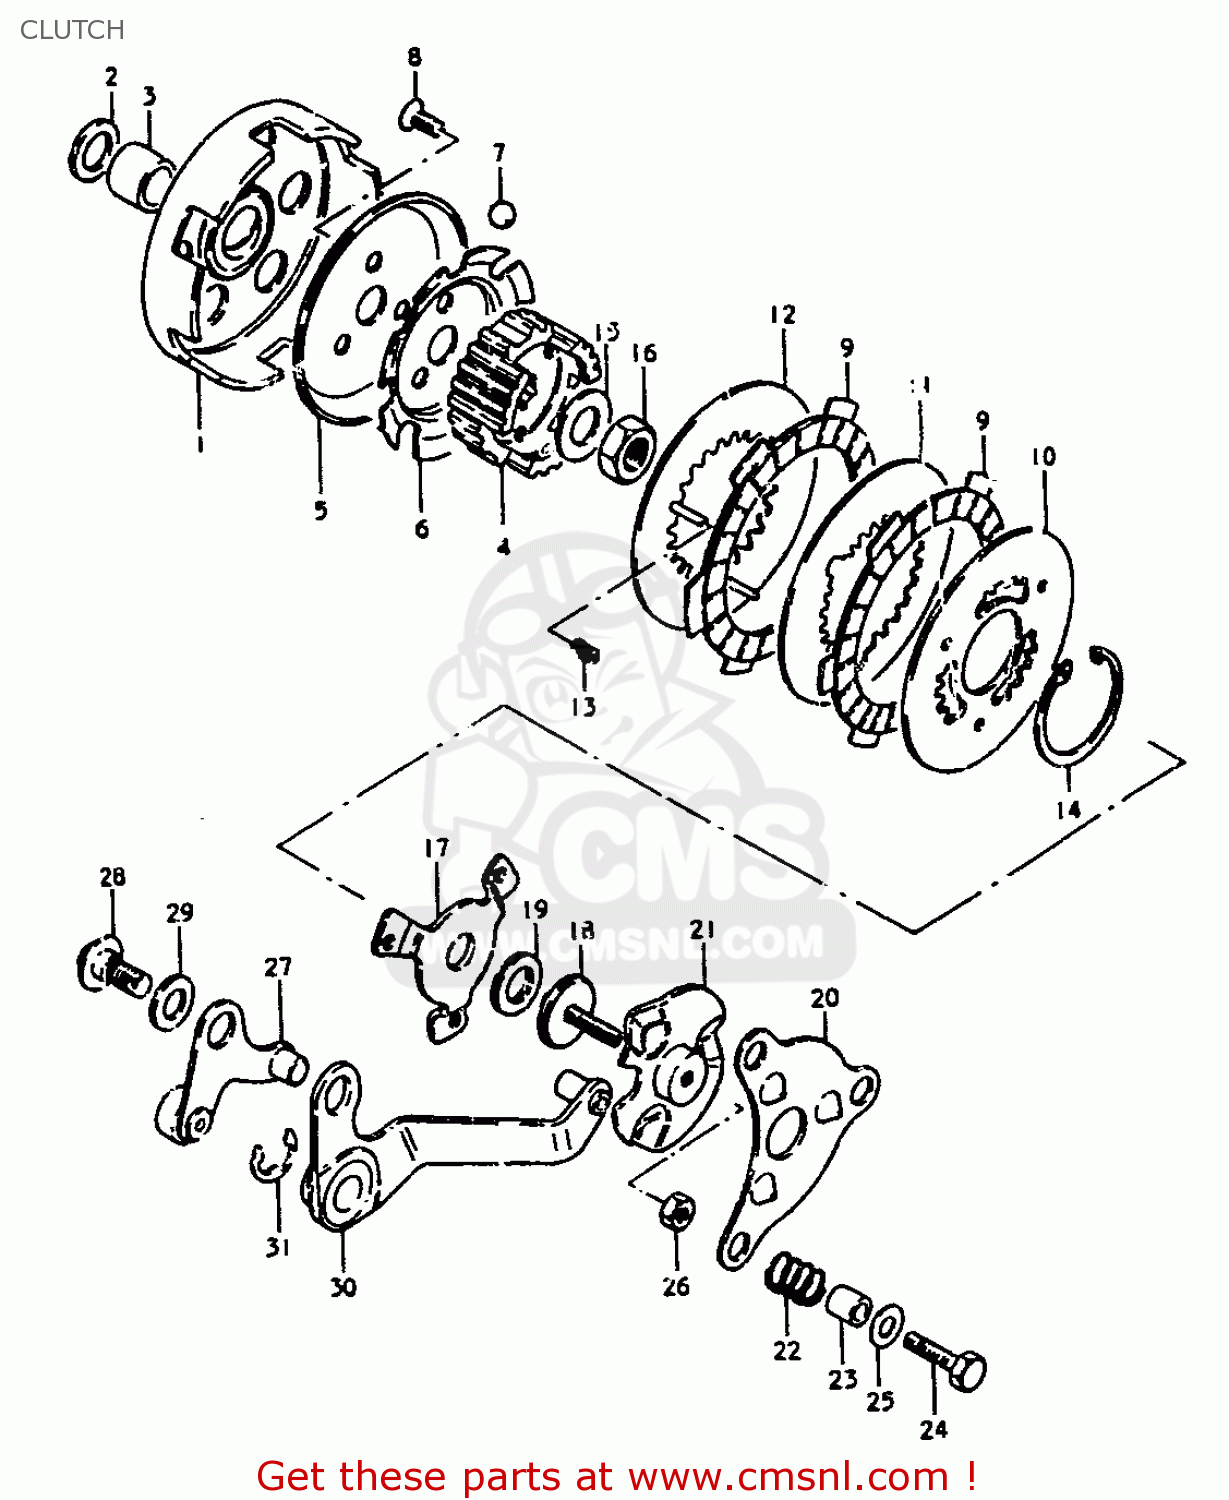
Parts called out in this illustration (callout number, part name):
1	GEAR,PRIMARY DRIVE
2	WASHER(14X23X3)
3	SPACER(14X19X18)
4	HUB,CLUTCH SLEEVE
5	PLATE,CLUTCH BALL
6	GUIDE,CLUTCH BALL
7	BALL
8	SCREW
9	PLATE,CLUTCH DRIVE (NAS)
10	PLATE,CLUTCH DRIVEN OUTER (NAS)
11	PLATE,CLUTCH DRIVEN (NAS)
12	PLATE,CLUTCH INNER
13	SPRING
14	CIRCLIP
15	WASHER
16	NUT
17	PLATE,CLUTCH PRESSURE
18	PIECE,CLUTCH PUSH
19	BEARING(10X22X2.8)
20	PLATE,CLUTCH RELEASE
21	PLATE,CLUTCH RELEASE,INNER
22	SPRING
23	SPACER(6X9X10.3)
24	BOLT
25	WASHER
26	NUT 6MM
27	PLATE,CLUTCH RELEASE ARM LINK
28	BOLT(8X17)
29	WASHER
30	ARM,CLUTCH RELEASE PLATE
31	E RING
